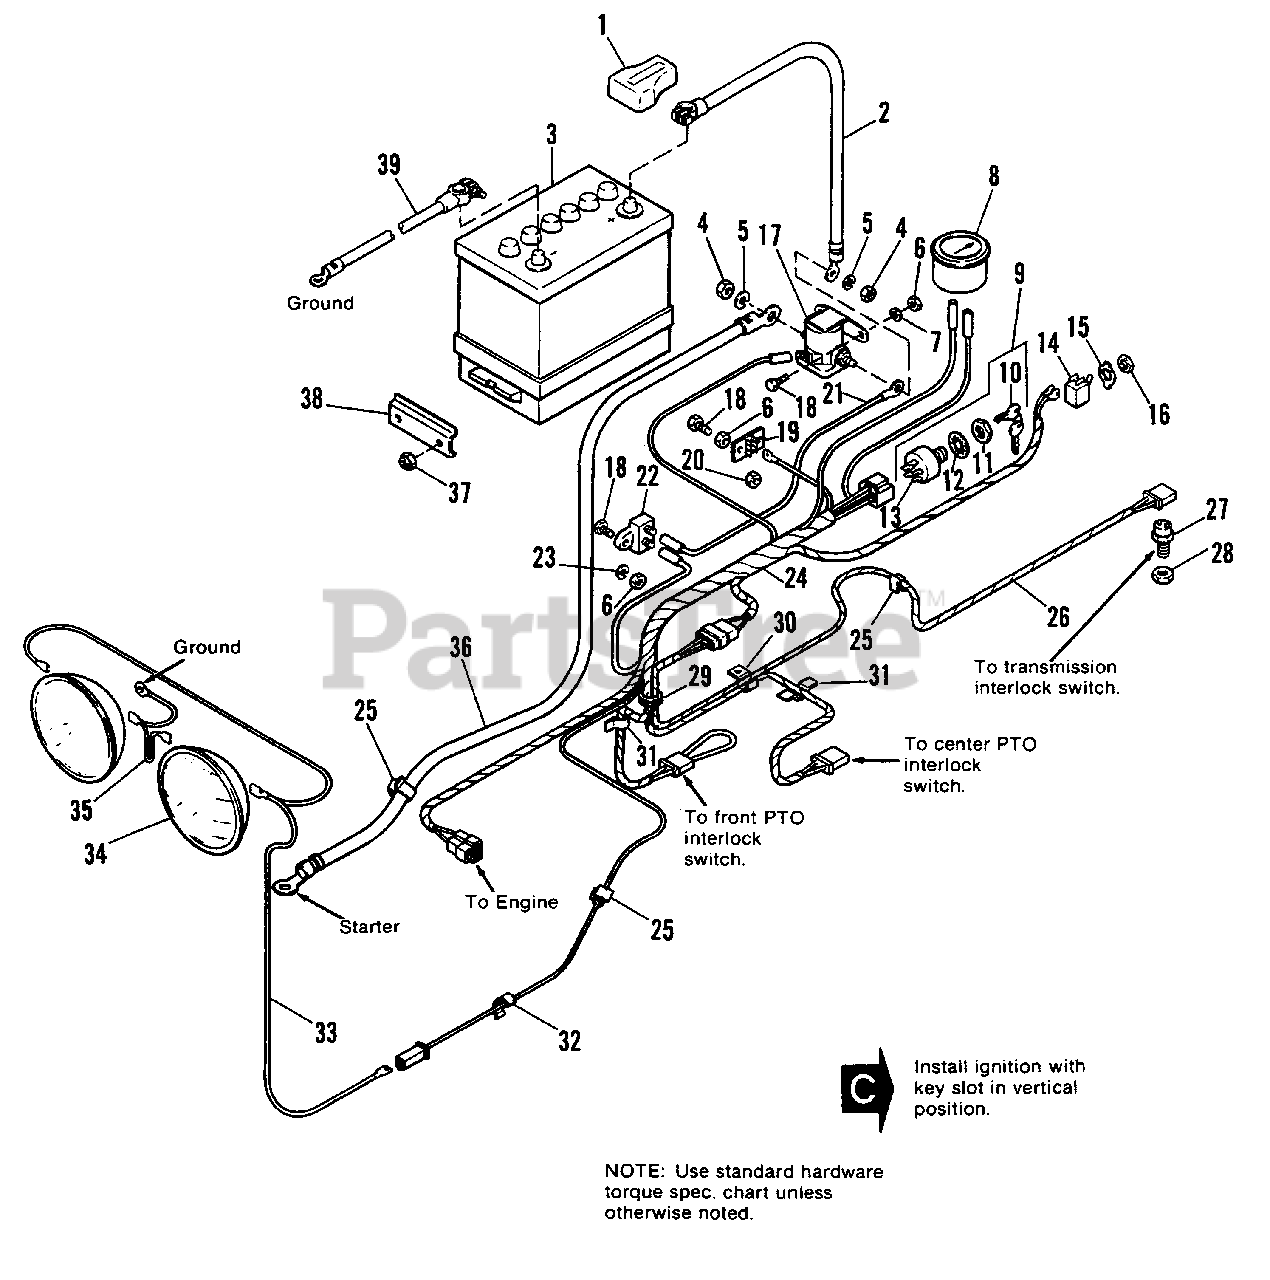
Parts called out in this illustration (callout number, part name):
1	PROTECTOR, Terminal
2	CABLE, Battery to Solenoid
3	BATTERY (includes decal)
4	NUT, Hex, 5/16-18
5	LOCKWASHER, 5/16
6	NUT, Hex, 1/4-20
7	LOCKWASHER, 1/4
9	SWITCH & KEY ASSY., Ignition
11	NUT, Special
12	LOCKWASHER, Internal Tooth, 5/8
13	SWITCH, Ignition
14	SWITCH, Toggle
16	NUT, Switch
17	SOLENOID, Starter
18	CAPSCREW, Hex Hd., 1/4-20 x 5/8
19	BOARD, Terminal
20	LOCKNUT, Hex, 1/4-20
22	CIRCUIT BREAKER
23	LOCKWASHER, 1/4
24	HARNESS ASSY.
25	CLIP, Tinnerman
26	WIRE ASSY.
27	SWITCH, Interlock
28	NUT, Pal
30	CLIP, Cable
31	CLIP, Wire
32	CLIP, Tinnerman
35	WIRE ASSY.
36	CABLE, Solenoid to Starter
37	NUT, Elastic, 5/16-18
39	CABLE, Battery to Ground
